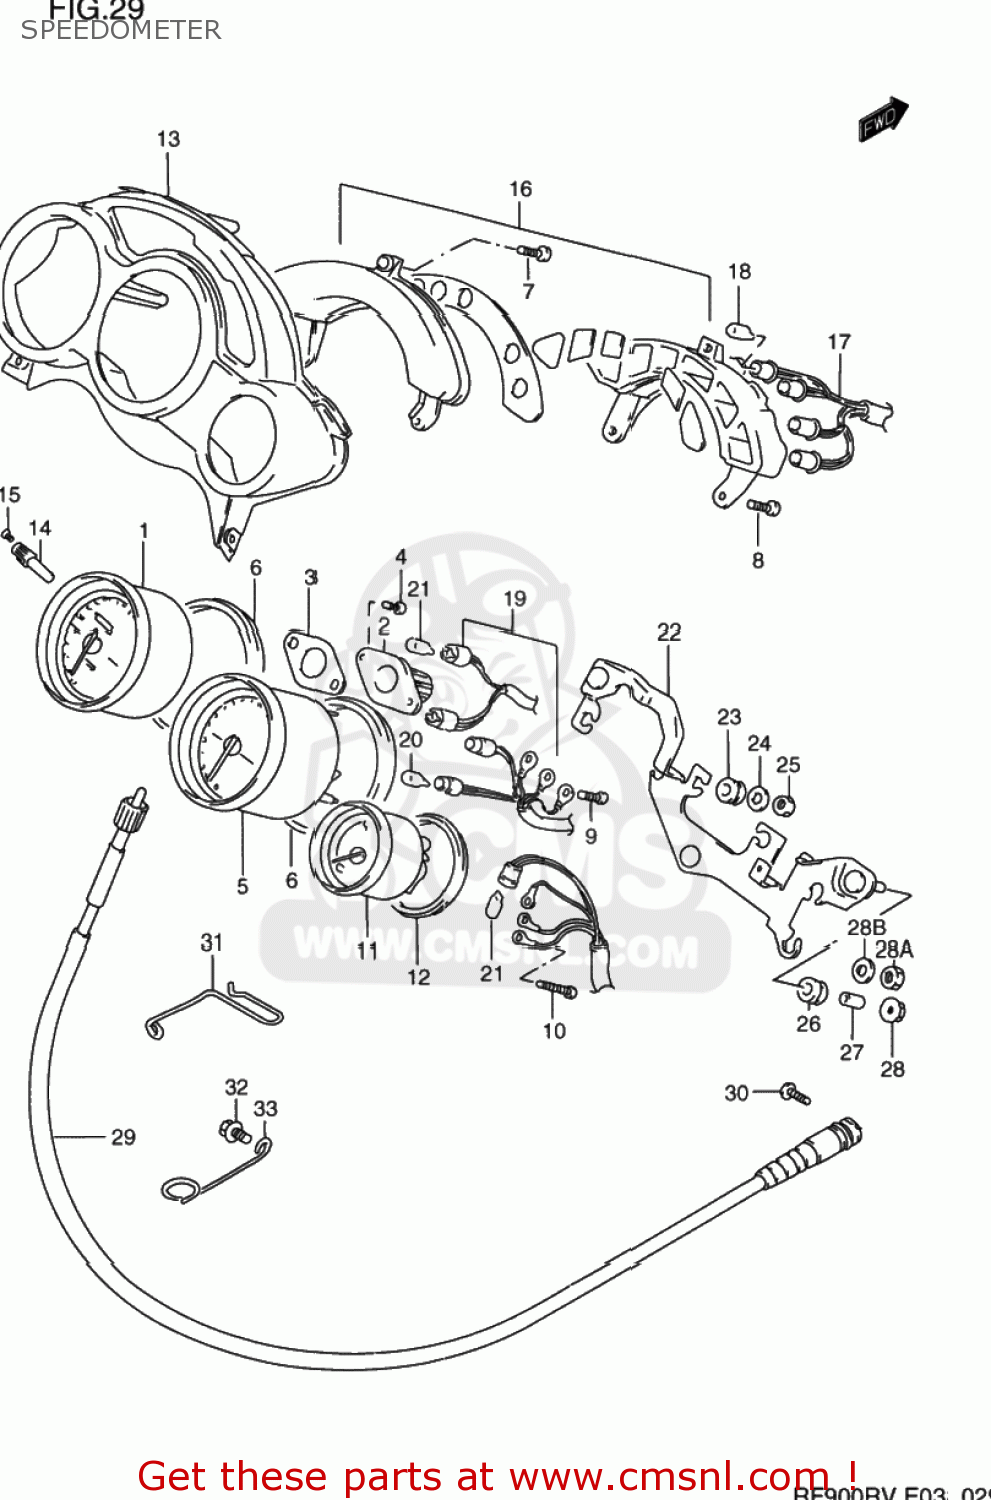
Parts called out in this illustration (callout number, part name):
1	SPEEDOMETER
2	GEAR BOX
3	GASKET,METER GEAR BOX (NAS)
4	SCREW
5	TACHOMETER
6	CUSHION,METER
7	SCREW
8	SCREW
9	SCREW
10	SCREW(3X22)
11	TEMP METER
12	CUSHION,TEMP METER
13	VISOR
14	KNOB,TRIP METER
15	SCREW(2X6)
16	BOX ASSY,PILOT
17	CORD ASSY,PILOT BOX
18	BULB(12V3.4W,T10,BF175-01450A)
19	CORD ASSEMBLY
20	BULB(12V1.7W,WB372,T7)
21	BULB(12V1.7W,T6.5)
22	BRACKET,METER
23	CUSHION,METER
24	WASHER,METER
25	NUT
26	CUSHION
27	SPACER (6.1X8X9.5)
28	NUT
28A	NUT
28B	WASHER(6.5X18X1)
29	CABLE ASSY,SPEEDOMETER
30	SCREW
31	GUIDE,SPEEDOMETER CABLE
32	BOLT
33	GUIDE,SPEEDOMETER CABLE NO.3
